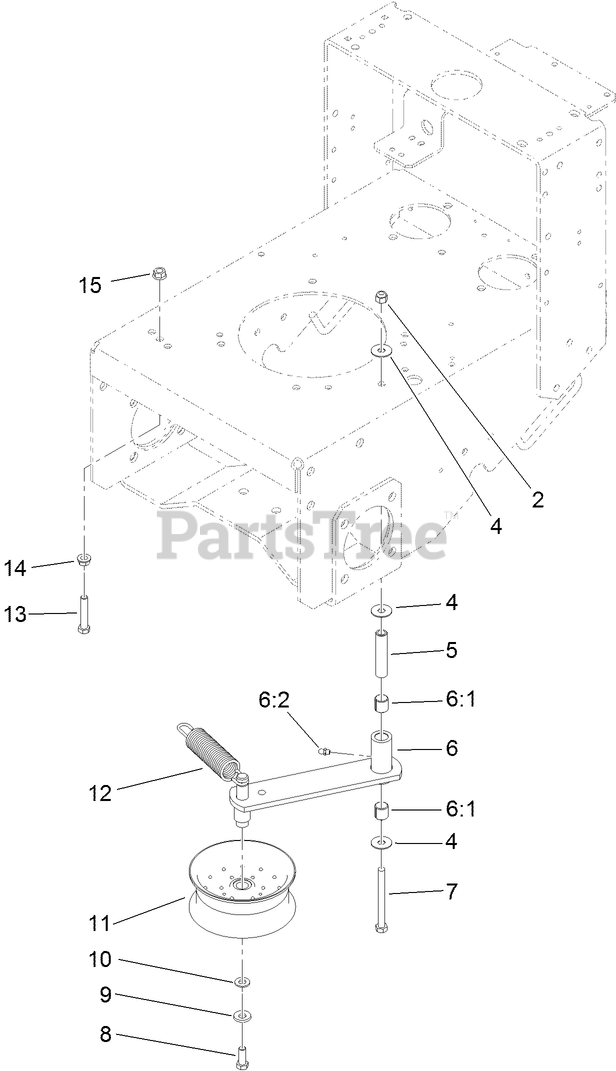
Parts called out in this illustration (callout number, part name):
2	NUT-LOCK, NI
4	WASHER
5	TUBE-IDLER
6	IDLER ARM ASM
6:1	SLEEVE-BEARING
6:2	FITTING-GREASE
7	SCREW-HH
8	SCREW-HH
9	WASHER-BELLEVILLE
10	WASHER-FLAT
11	IDLER-PULLEY, FLAT
12	SPRING-EXTENSION
13	SCREW-HH
14	NUT-HHF, WHIZ
15	NUT-HF
